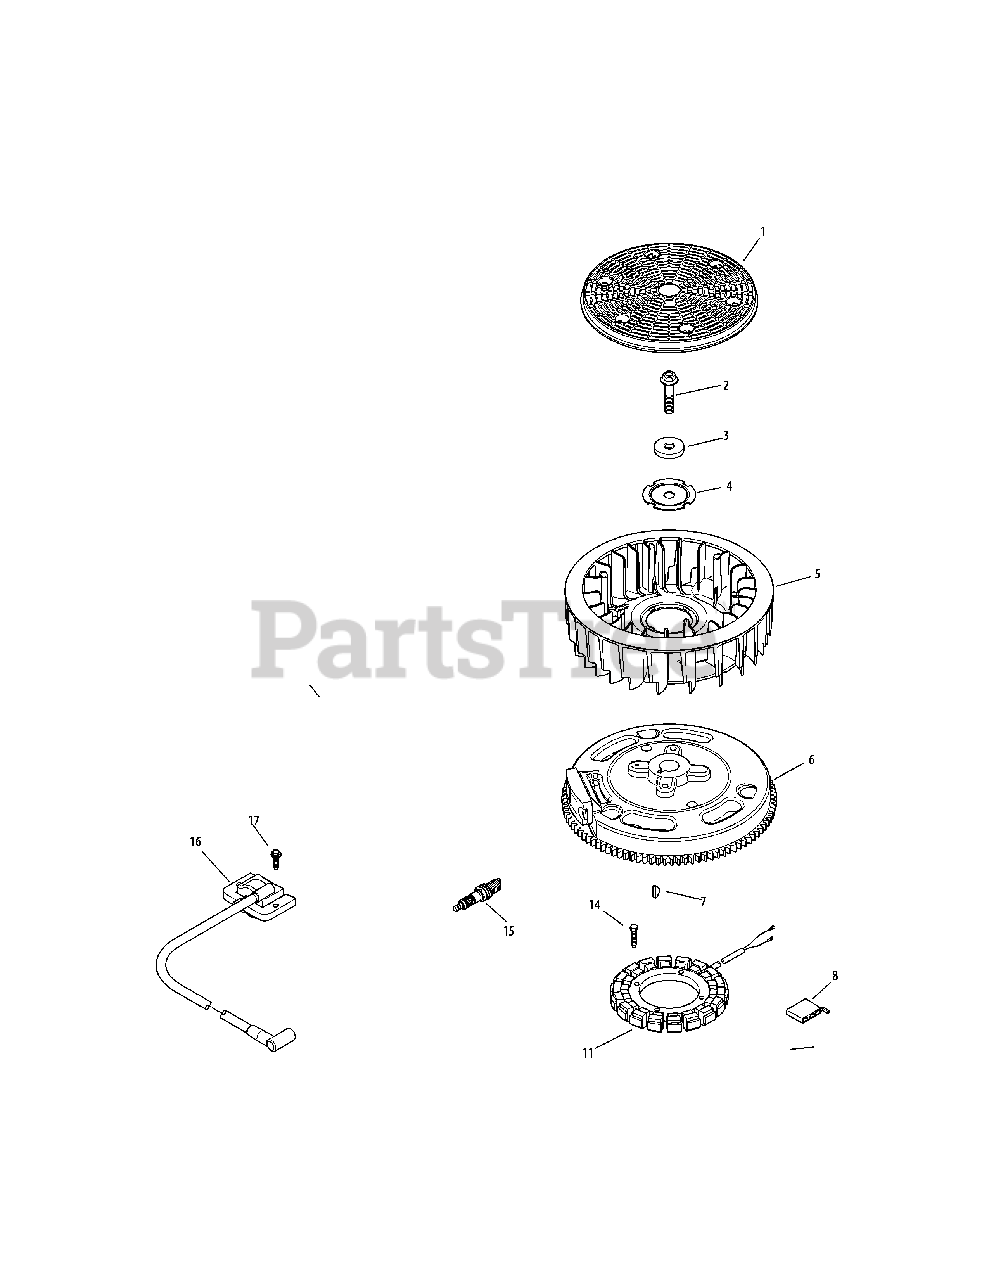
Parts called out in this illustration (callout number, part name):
2	Flg. Screw, M 10 X 1.5 X 45
3	Flat Washer, 13/32
4	Fan Mounting Plate
5	15 Amp Stator Kit (Inc. KH-25-452-01-S)
6	Flywheel Assembly
7	Key, 3/16 X 5/8
11	15 Amp Stator Kit
14	Thd. Frm. Screw, M5 X 0.8 X 25
15	Spark Plug
16	Module Ignition Kit
17	Flg. Thd. Frm. Screw, M5 X .8 X 20
